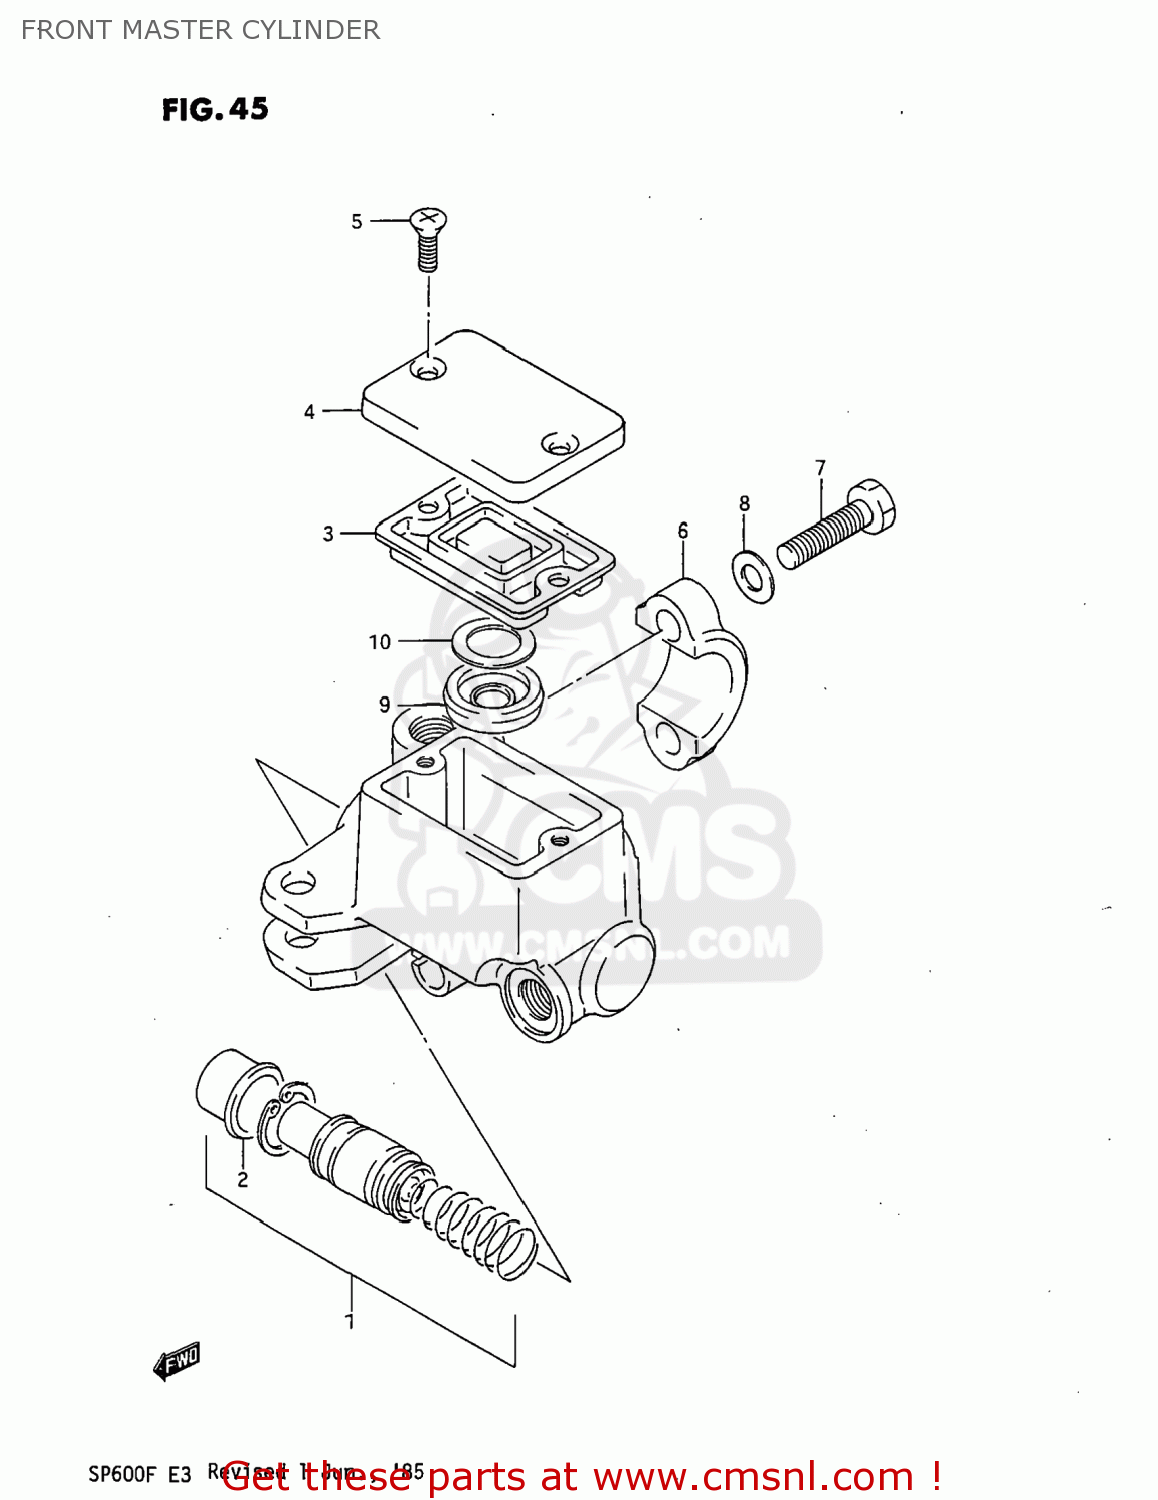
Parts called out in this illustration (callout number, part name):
1	PISTON & CUP SET
2	BOOT
3	DIAPHRAGM
4	CAP
5	SCREW
6	HOLDER
7	BOLT
8	WASHER
9	SEPERATOR
10	PLATE
